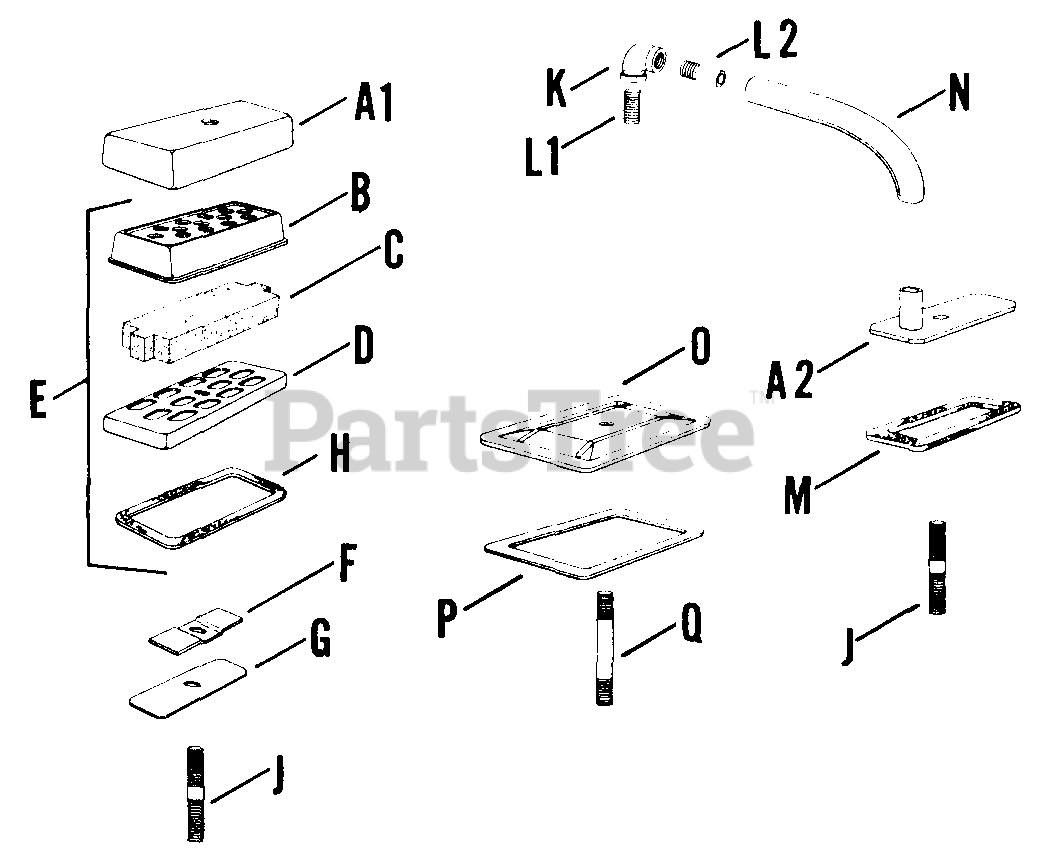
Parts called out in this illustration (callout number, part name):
A1	COVER - DISCONTINUED
D	BAFFLE - DISCONTINUED
E	BREATHER - DISCONTINUED
F	BAFFLE, BREATHER
G	REED - DISCONTINUED
H	GASKET - DISCONTINUED
J	STUD - USE X-352-39
O	COVER, VALVE (#DSC)
P	GASKET - DISCONTINUED
Q	STUD - USE 220368
